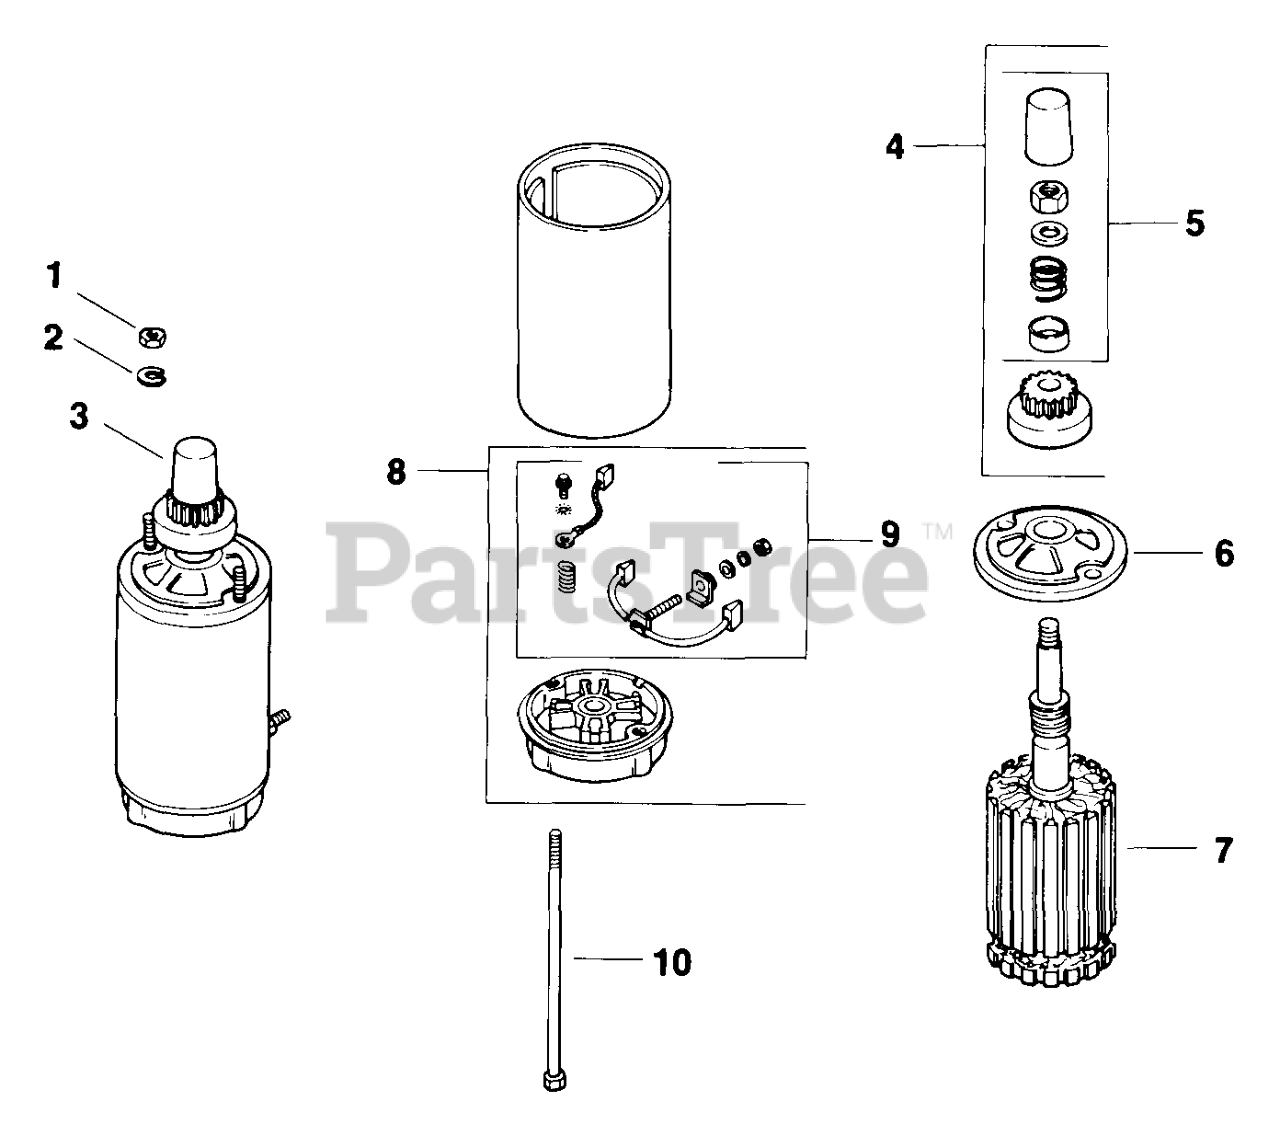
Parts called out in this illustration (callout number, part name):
1	NUT, 1/4-20 GRADE 2 USE 25 100 20-S
2	WASHER, SPRING LOCK 1/4"
3	STARTER - USE 52 098 12
4	DRIVE KIT - USE 82 755 32
5	DRIVE - USE 82 755 32
6	KIT - USE 82 755 32
7	ARMATURE - (#DSC)
9	KIT - USE 52 755 15
